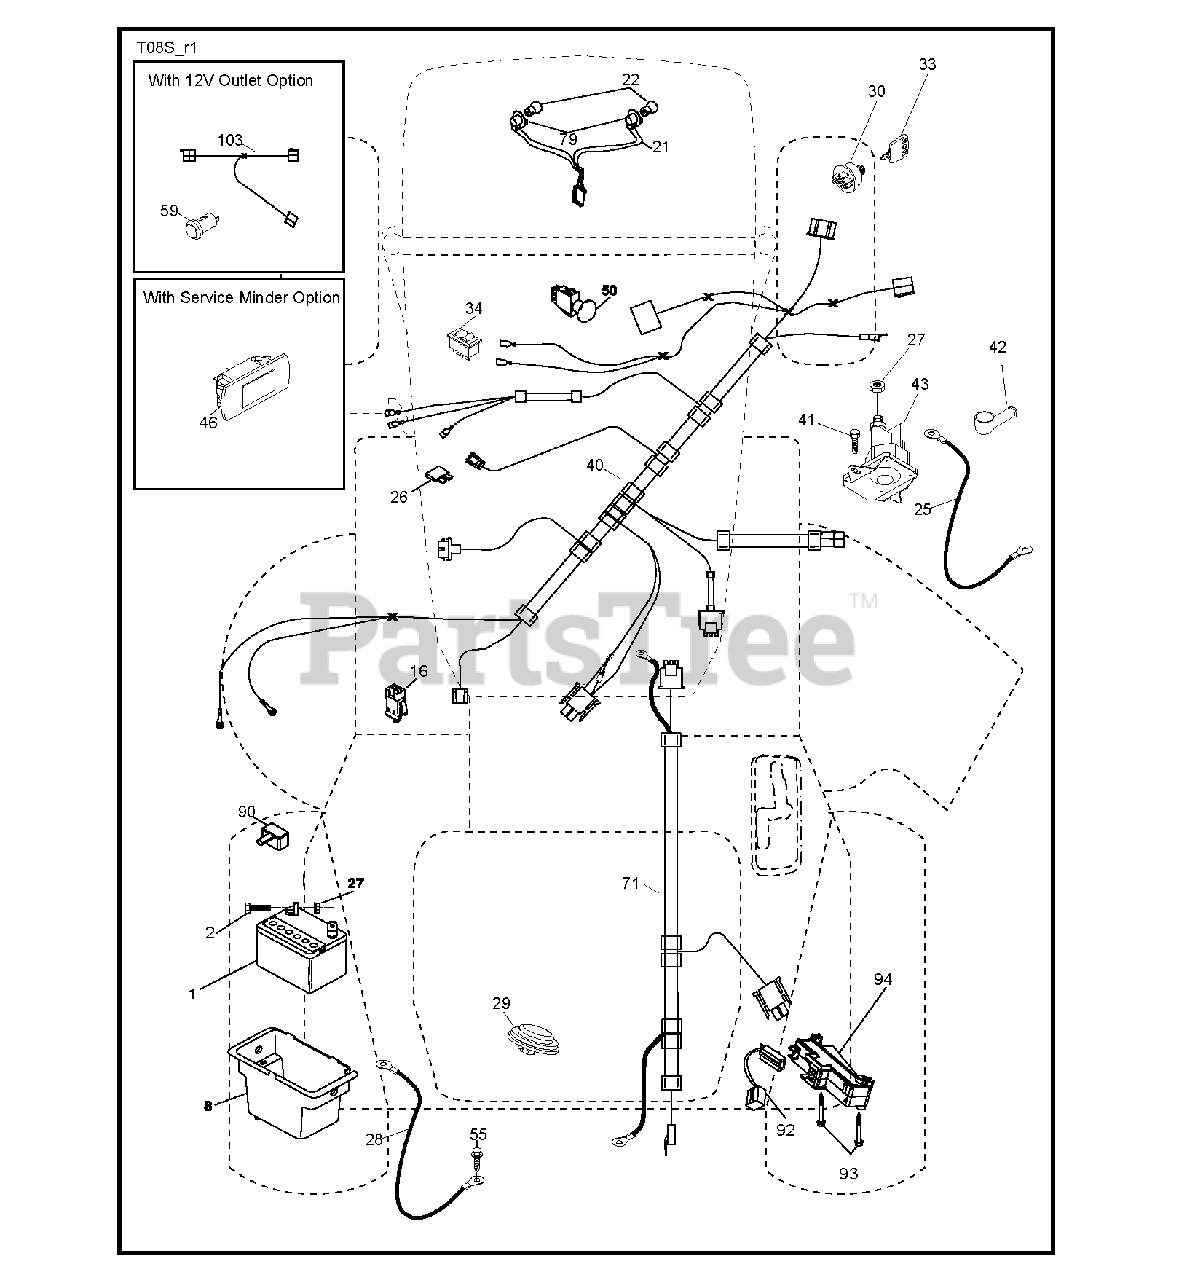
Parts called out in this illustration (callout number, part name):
1	REPL BY 532 12 38-99
8	BOX.BATTERY.MNT.REAR.L
16	SWITCH INTERLOOK PUSH-IN
21	HARNESS.LIGHT W/4152J BULBS
22	LIGHTBULB
25	CABLE.STARTER.6G.BL/RED.17.5
26	FUSE 20AMP
27	NUT
28	CABLE.BLACK.18"REAR.BA
29	SWITCH.SEAT.DELTA.OPC.
30	SWITCH.IGN.DELTA.W.LGH.ROS
33	KEY.CHAIN.BLISTER.PACK.GEN.INT
34	SWITCH LT
40	HARNESS.IGN.DASH.HUQ/P
41	SCREW
42	TERMINAL COVER
43	SOLENOID.W/BRASS.PLUNG
50	PTO SWITCH
55	SCREW 5/16"
71	HARNESS.IGN.CHASS.TEX.REAR.BAT
79	BULB HOLDER ASM.
90	COVER, TERMINAL BATTERY
92	HARNESS.PIGTAIL.CONSLE
93	SCREW.PLASTITE
94	MODULE.REVERSE.ROS
